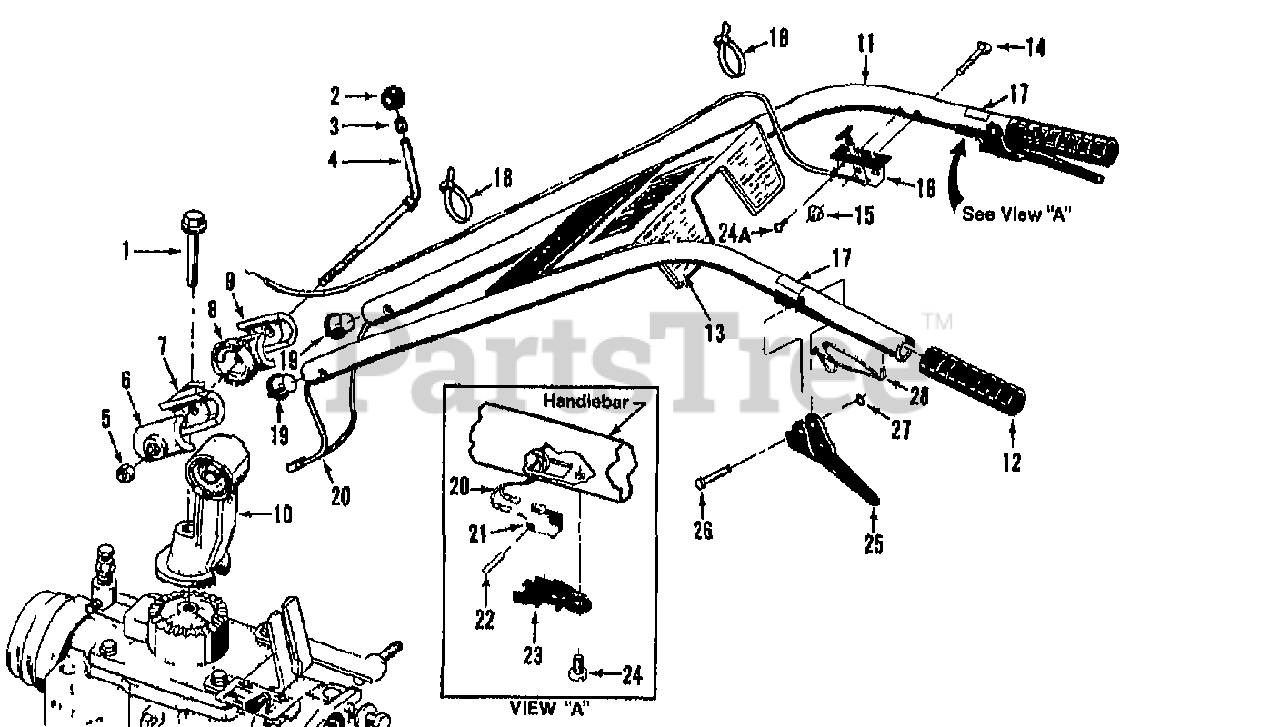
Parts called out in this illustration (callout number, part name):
1	BOLT 1/2-13X3.5 FH GR5
2	KNOB-CONTROL (INCL. #3)
3	RING-TOLERANCE .5325 ID
4	STUD-H/BAR W/NUT & RING (INCL. # 2,3 & 5)
5	NUT-HEX JAM 1/2-13
6	CLAMP-LH HORSE 1021-1
7	RATCHET-H/BAR RED 2542-1
8	RATCHET-RH RED HORSE 2542-2
9	CLAMP-RH HORSE 1021-2
10	BASE-H/BAR RED 2534A
11	ASSM-HANDLEBAR W/GRIPS (INCL. #12,13,17, & 28)
12	GRIP-H/BAR SMOOTH
13	DECAL-CONTROL PANEL HORSE
14	BOLT-CH 1/4-20X2.00 ZP
15	NUT-HF/LK 1/4-20 ZP
16	CABLE-THROTTLE 7 I/C B&S (SEE REF #24A)
17	DECAL-FWD INTERLOCK
18	TIE-RED
19	RETAINER-HARNESS H/B OPC
20	HARNESS-WIRE OPC HORSE
21	SWITCH-H/B OPC
22	PIN-LK .11X.58 HORSE OPC
23	HOUSING-SWITCH OPC
24	SCR-HW M10-24X.5 STH ZP
24A	SCR-PHS M10-32X.5 STH ZP
25	LEVER-HORSE OPC
26	PIN-PIVOT OPC LEVER
27	RING-KLIP 5304-25
28	SPRING-H/B LEVER
